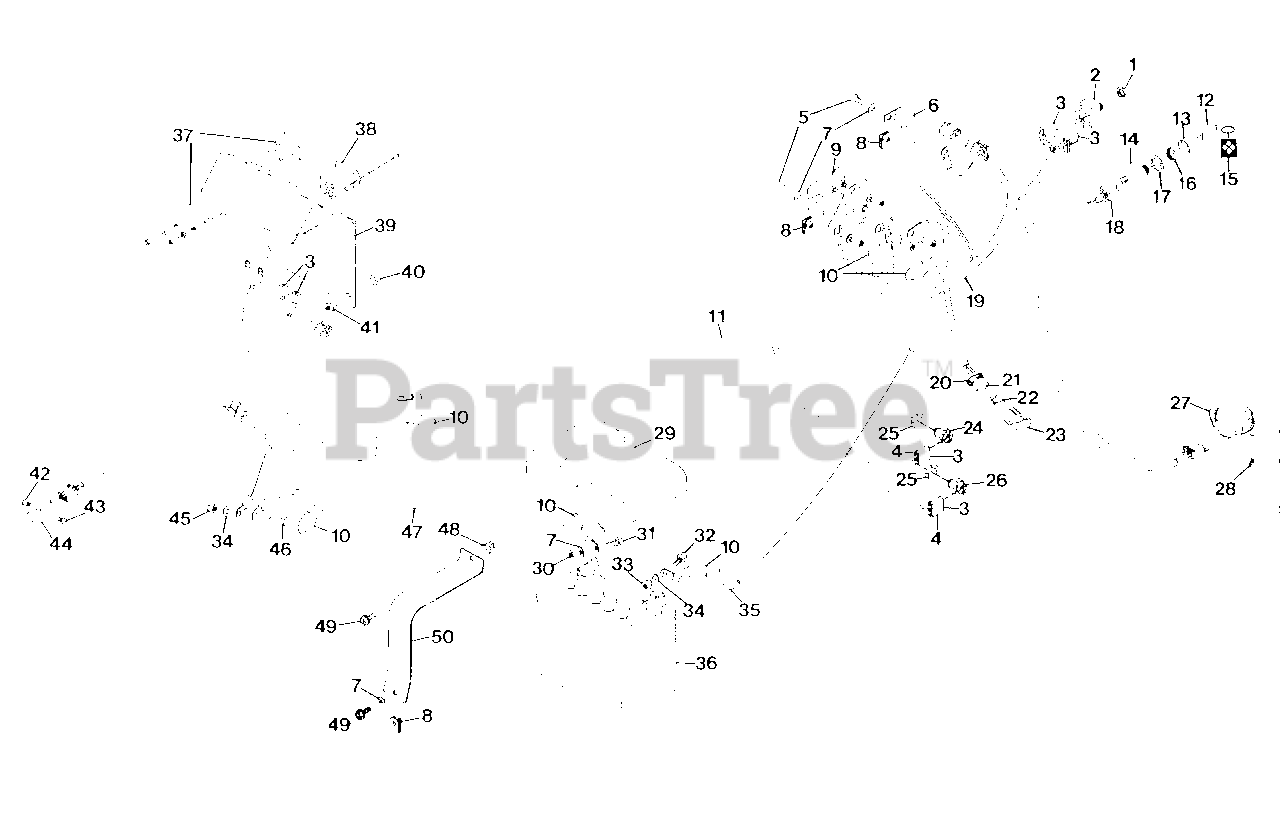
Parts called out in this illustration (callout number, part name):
1	NUT, 1/2-27
2	SWITCH, PTO
3	TERMINAL
4	CONNECTOR, 2-WIRE SWITCH
5	SCREW, MACHINE 1/4-20 PHD
6	MODULE, INTERLOCK
7	WASHER, FLAT .281X.625X.065
8	NUT, SPEED 1/4-20
9	SWITCH, MAGNETIC
10	BOOT, BATTERY CABLE
11	ASSEMBLY, CABLE
12	KEY, IGNITION SWITCH
13	BOOT, 9/16 SWITCH
14	SWITCH, IGNITION
15	CHAIN, KEY
16	NUT, JAM 9/16-24
17	WASHER, LOCK 9/16 INT. TOOTH
18	CONNECTOR
19	HARNESS, WIRING
20	CONNECTOR
21	TERMINAL, 14-16 GAUGE
22	FUSE, 25 AMP
23	COVER
24	SWITCH, NEUTRAL START
25	NUT, STAMPED 9/16-18
26	SWITCH, INTERLOCK
27	SWITCH, SEAT
28	SCREW, MACHINE 1/4-20
29	COVER, BATTERY
30	NUT, HEX 1/4-20
31	BOLT, HEX 1/4-20-X.625
32	BOLT, HEX 5/16-18X.625
33	NUT, HEX 5/16-18
34	WASHER, FLAT .344X.688X.065
35	CABLE, BATTERY TO SOLENOID
36	BATTERY, 12 VOLT
37	GAUGE, AMMETER
38	HOURMETER
39	SILKSCREEN, GAUGE PANEL
40	BOLT, HEX 3/8-16X1.125
41	NUT, LOCK 3/8-16
42	NUT, LOCK 10-24
43	SCREW, MACHINE 10-24X.625 PHD
44	SWITCH, INTERLOCK
45	NUT, LOCK 5/16-18
46	BOLT, HEX 5/16-18X1.00
47	CABLE, NEGATIVE BATTERY
48	GROMMET, PLASTIC
49	SCREW, 1/4-20X.50 SELF TAPPING
50	STRAP, BATTERY
